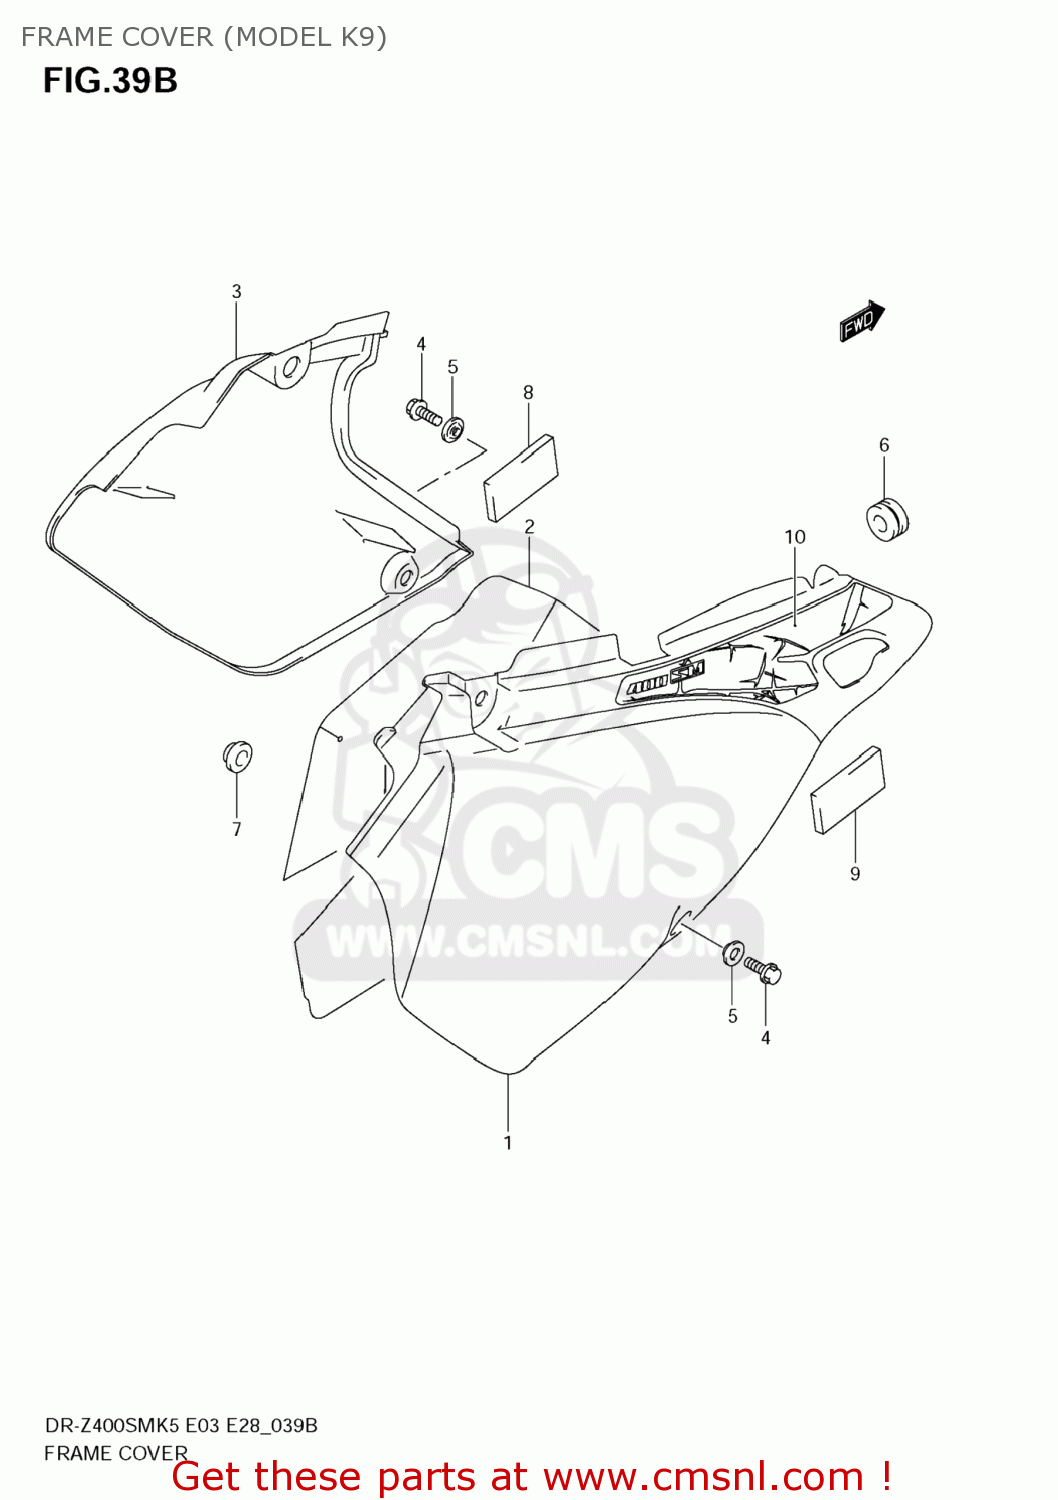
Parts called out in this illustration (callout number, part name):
1	COVER,FRAME,R(BLACK)
2	SHIELD,FRAME COVER,R
3	COVER,FRAME,L(WHITE)
4	BOLT(6X12)
5	WASHER
6	CUSHION
7	CUSHION
8	CUSHION,FRAME COVER,L
9	CUSHION
10	TAPE,FRAME COVER,R
